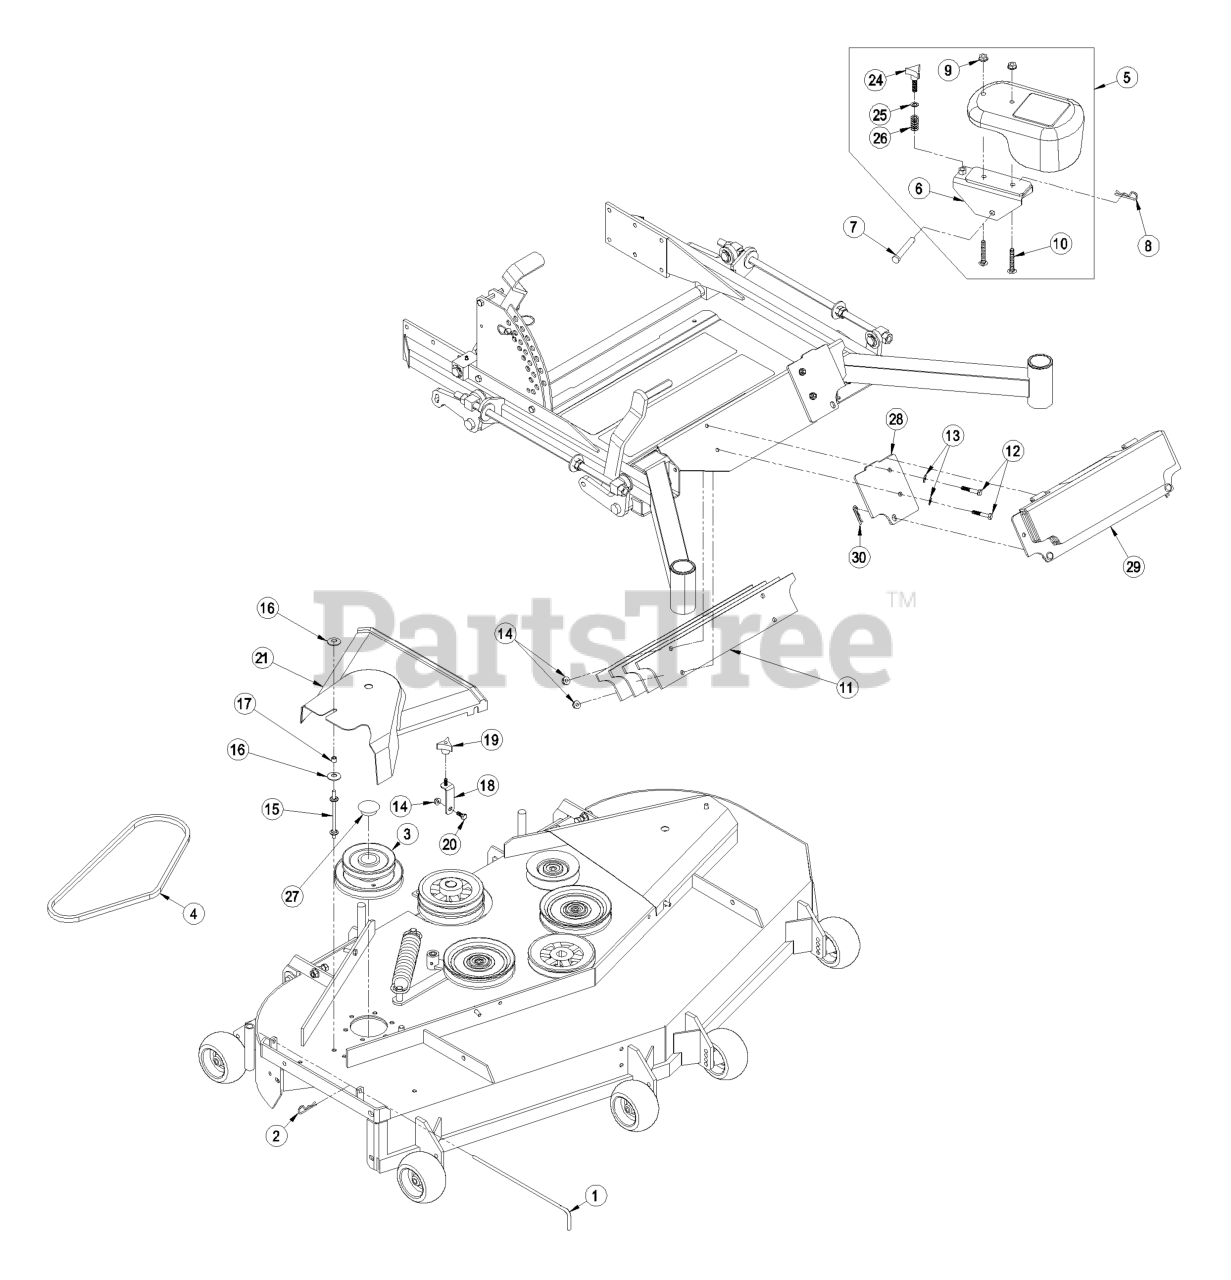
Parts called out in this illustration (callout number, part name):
1	PIN, CHUTE PIVOT
2	PIN-COTTER
3	JACKSHAFT, LZUV60
4	BELT, BLOWER DRIVE 60
5	ASM, WEIGHT 1.5" 70 POUND
6	WLD, BRACKET 2.0 ARM
7	PIN-CLEVIS
8	PIN-COTTER
9	NUT-HHF, WHIZ
10	BOLT, SQUARE HEAD YZ
12	SCREW-HH
13	WASHER-PLAIN
15	STUD,BELT SHIELD 4 INCH
16	WASHER-SPRING
18	Support, Belt Cover
19	Knob
21	COVER, BELT 60
25	WASHER-FLAT
27	PLUG, BLACK NYLON 1.75
28	PLATE, WEIGHT MOUNTING
29	ASM, WEIGHT PLATE WITH DE
30	PIN-HAIR
